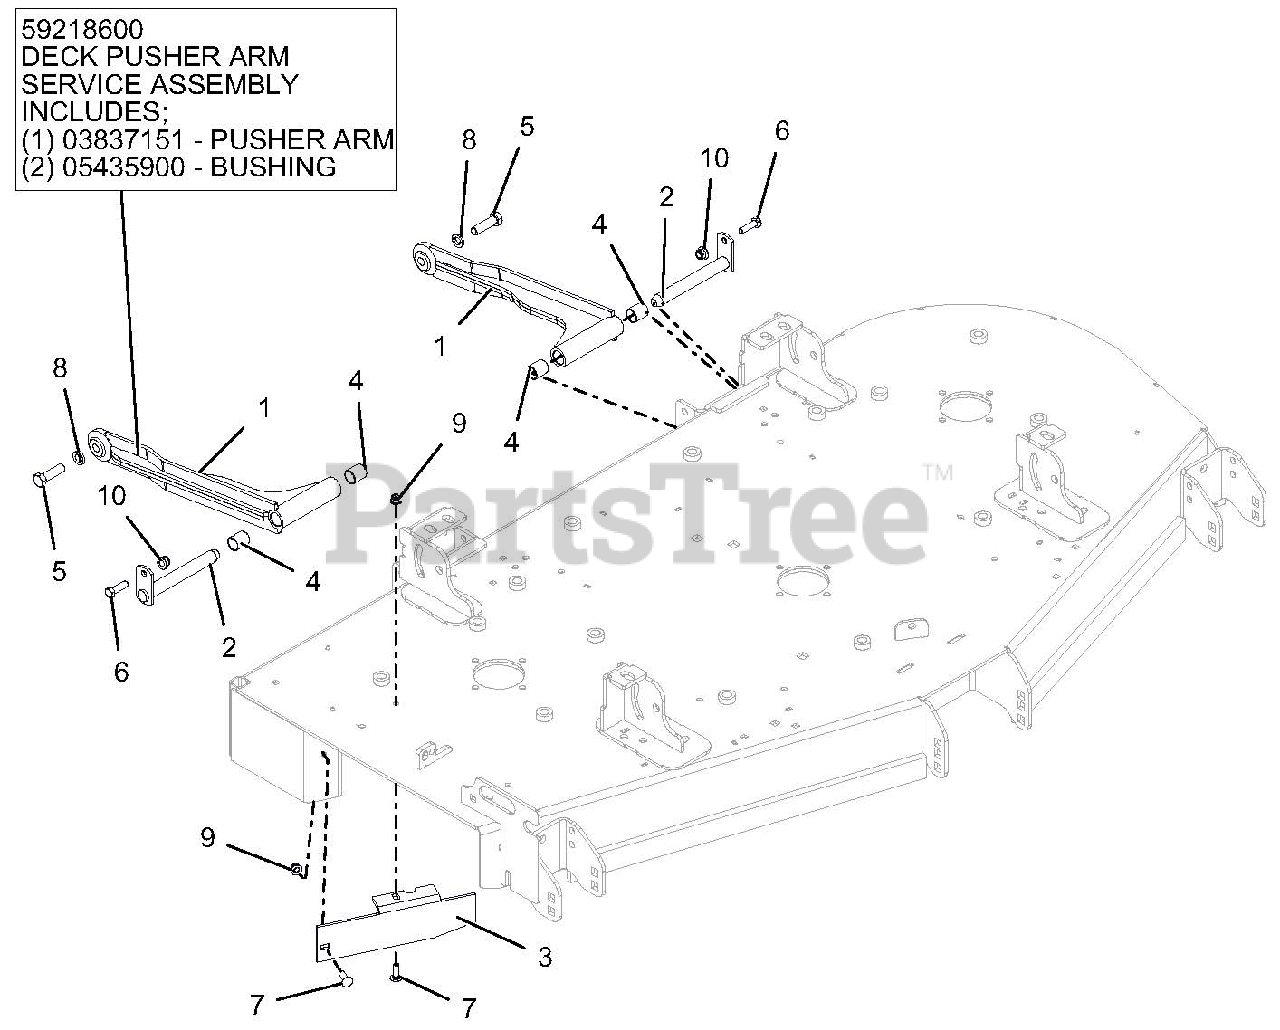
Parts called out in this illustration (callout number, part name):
1	DECK STABILIZER ARM - BLACK
1	DECK STABILIZER ARM W/BUSHINGS
1	BRG, .750 X .875 X 1.000
2	WELDMENT, MOWER MTG. PIN
3	60" DISCHARGE BAFFLE - RED
4	BRG, .750 X .875 X 1.000
5	BLT-HEX .50-13X1.75 GR5EP80 YZ
6	@BLT-HEX .38-16X1.25 GR5 YWZC
7	@BLT-RDHDSQNK .31-18X1.00 G5YZ
8	@WSHR-LK .50X.125 REG YWZC
9	@NUT-LK-NYL-FLG .31-18 YWZC
10	@NUT-LK-NYL-FLG .38-16 YWZC
